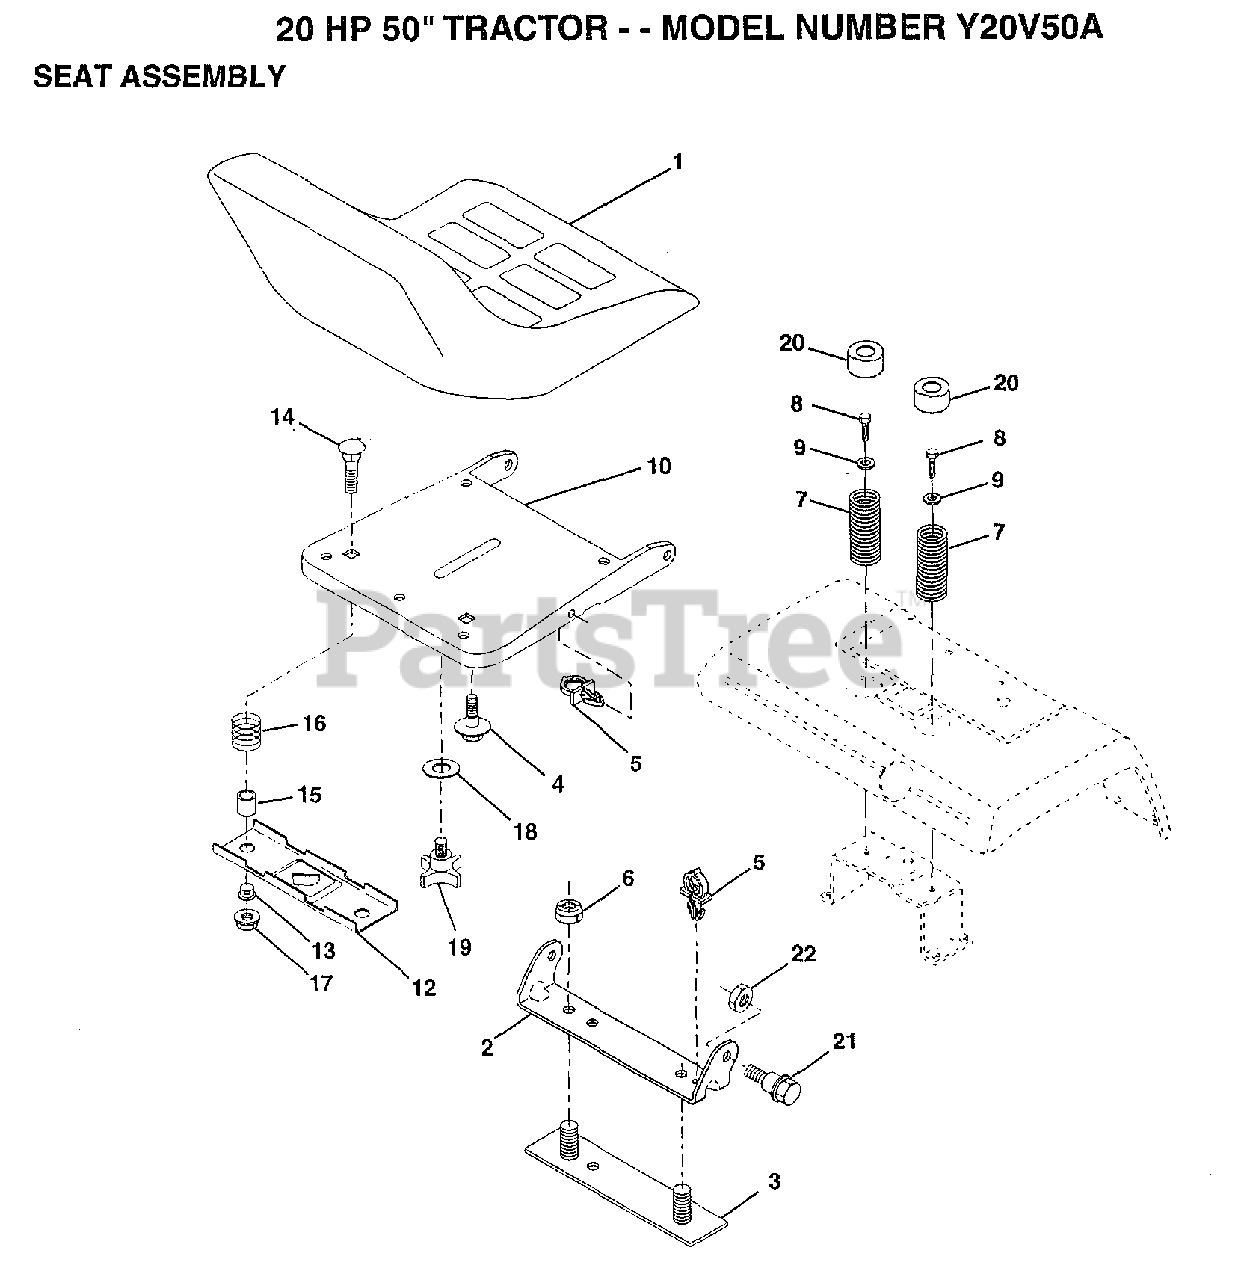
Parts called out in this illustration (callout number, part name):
2	BRACKET PVT SEAT
3	STRAP ASM FENDER
4	"BOLT,SHOULDER"
5	CLIP PUSH - IN
6	NUT
7	SPRING COMPRESSIO
8	SCREW LT
9	WASHER
12	BRKT SWITCH
13	BUSHING
15	SPACER SPLIT
16	SPRING COMPRESSED
18	WASHER
19	"KNOB 1/2"" YT"
20	CAP SPRING
21	BOLT.SHLD.5/16-18
